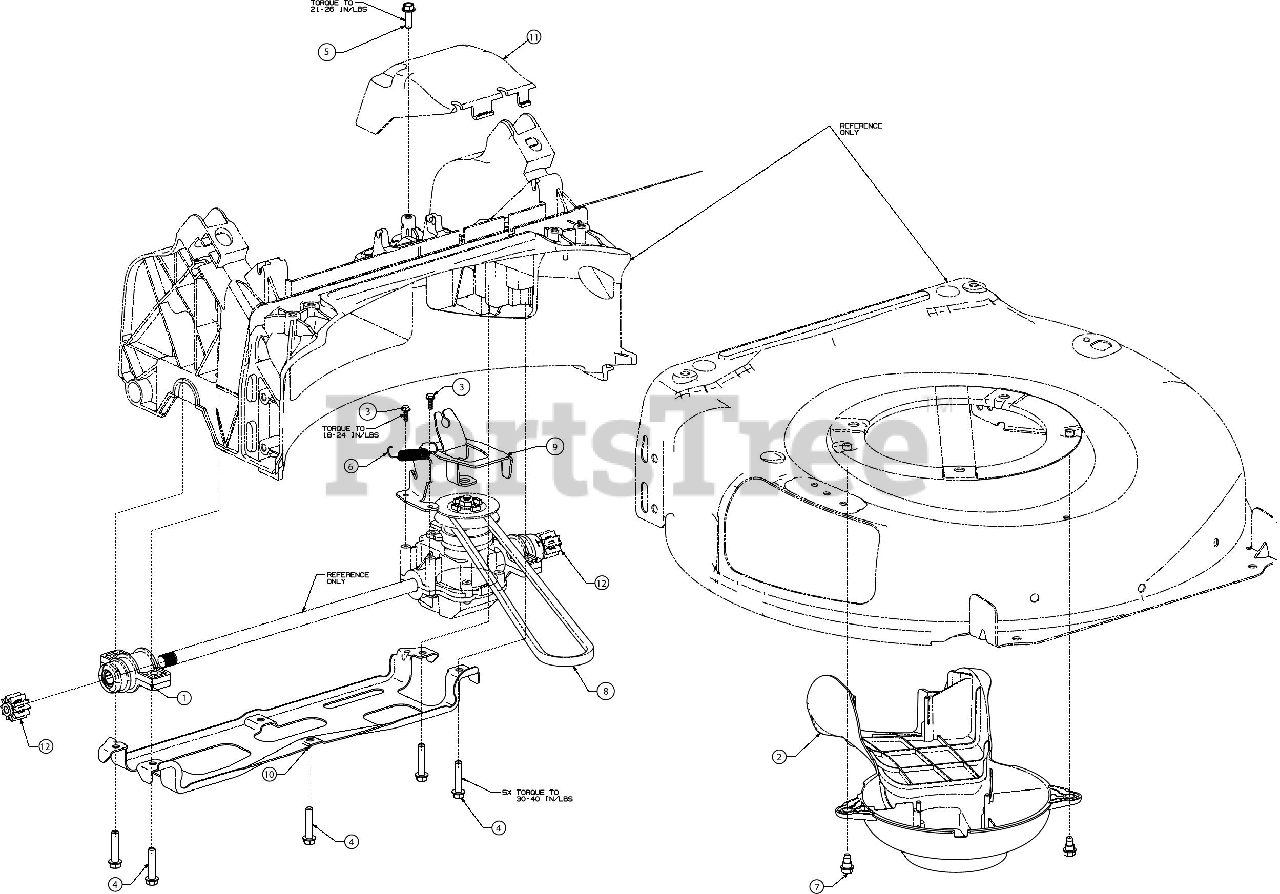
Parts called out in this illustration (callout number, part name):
1	BEARING ASSEMBLY
2	ENGINE BAFFLE ASSEMBLY
3	SCREW .159 x .43
4	SCREW 1/4-15 x 1.250
5	SCREW 1/4-15 x .750
6	EXTENSION SPRING
7	SHOULDER SCREW 1/4-20 x .50
8	V-BELT 31.25
9	TRANSMISSION BRACKET
10	BRACKET SUPPORT
11	TRANSMISSION COVER
12	SPUR GEAR 10T
